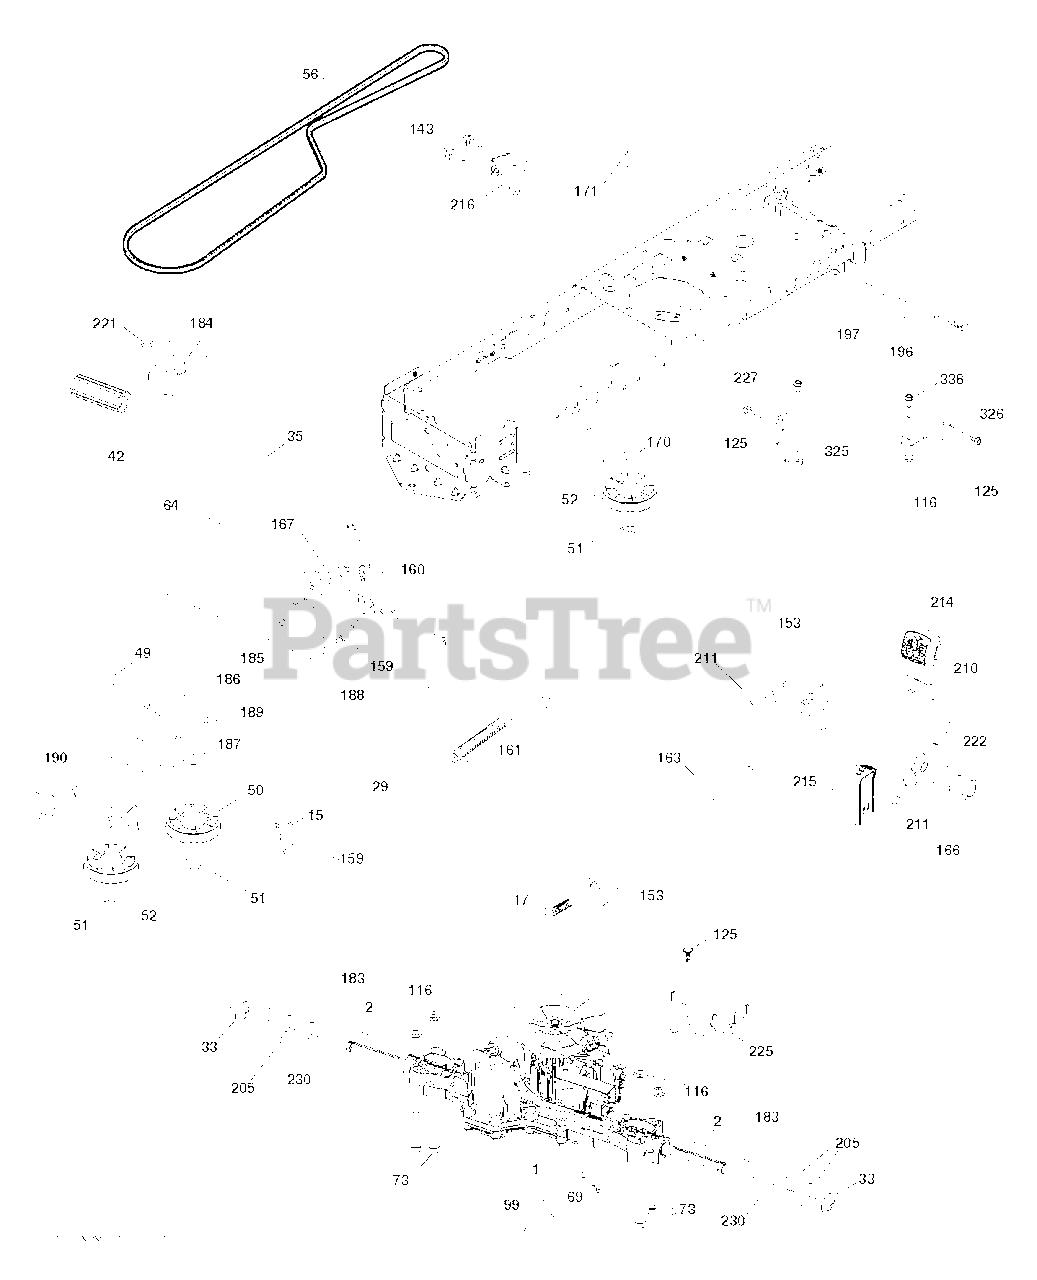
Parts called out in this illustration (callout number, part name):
2	SQUARE KEY
15	WASHER
17	SPRING.BRAKE.K46.GREEN
29	ROD.BRAKE.K46
35	ROD .BRAKE. PARKING. GT. HUSQ.
42	PEDAL COVER T
50	IDLER.FLAT.910.OFFSET
51	NUT LOCK FLG 3/8-16 UNC
52	IDLER.V-GROOVE.910.OFFSET
56	V-BELT.MOWER.92.40.42/K46
64	SHAFT.ASM.PEDAL.BRK.CNTR
69	HAIRPIN.SOFT.ZINC.059X1.125
99	ARM.PIVOTING.TCRD.GEN2.5.BAGGE
116	NUT LOCK HEX FLANGE 5/16-18
125	SCREW
143	SCREW LT
153	RETAINER M
159	COTTER PIN
160	RETAINER CLIP
161	SPRING, RETURN LT
163	ROD.CONTROL.K57R.K46
166	NUT.PUSH.625
167	LATCH.BRAKE.SPRING
170	KEEPER.V-IDLER.CENTER.
183	SPACER AXLE
184	HANDLE.PARKING.BRAKE.H (BLK)
186	SPACER.RETAINER
187	WASHER 12/32X2X10GA
188	LINK.CLUTCH.GROUND DRIVE.LONG
189	BELLCRANK.GROUND.DRIVE.TEX.
190	KEEPER.BELLCRANK.DRIVE
196	SCREW 3/8-16X1
197	CLUTCH.ANTIROTATION.WIREFORM.
210	ROCKER.ASM.PEDAL.CONTR
211	BEARING.NYLON
214	PEDAL.FORWARD.PAD.TEX
215	PEDAL.COVER.REVERSE.CRD.X498GY
216	BRACKET.PULLEY.IDLER.W/TEX
221	RETAINER.SPRING.CLIP.H
222	WASHER 21/32 X 1-1/4 X 10 GA.
225	KEEPER.BELT.TRANSAXLE.K46
227	SCREW
230	WASHER.HARDENED
325	BRACKET.TRQ.STP.46.20".TIRE.LH
326	BRCKT.PNT.TRQ.STP.46.20TIRE.RH
336	BOLT.5/16-18X1-3/4.FLANGED.HEX
